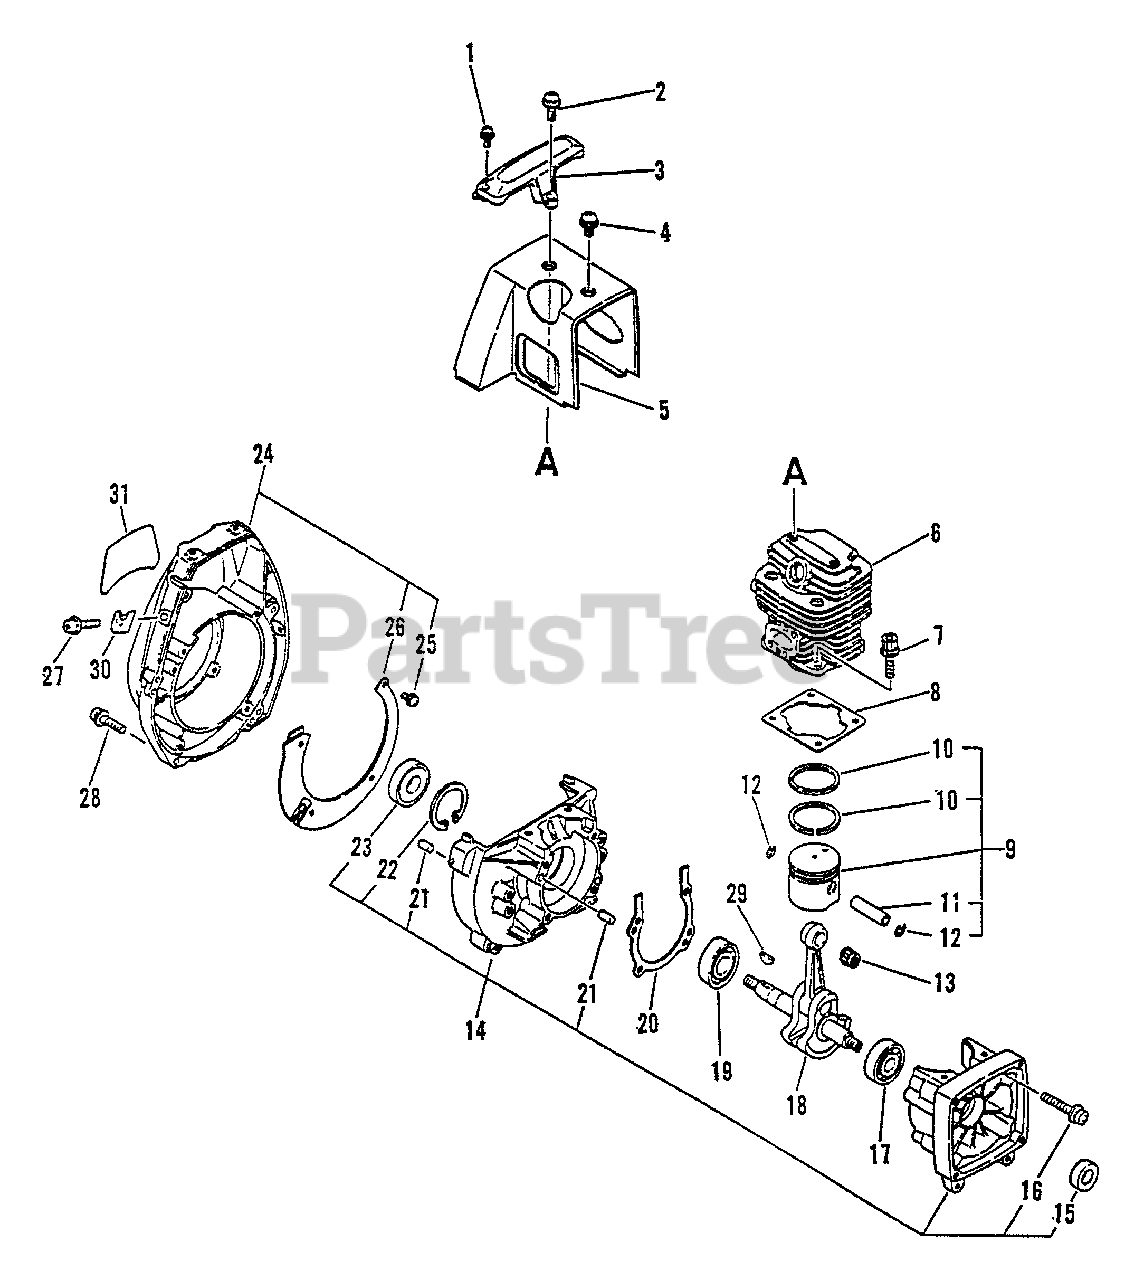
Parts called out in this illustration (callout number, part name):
1	SCREW - 4X14
2	SCREW - 5X16
3	GUARD - TOP
4	SCREW - 5X10
5	COVER, ENGINE
6	CYLINDER
7	SCREW - 5X20
8	GASKET, CYLINDER
9	PISTON KIT
10	RING, PISTON
11	PIN, PISTON
12	RING, RETAINING
13	BEARING, NEEDLE
14	CRANKCASE KIT
15	SEAL, OIL
16	SCREW - 5X30
17	BEARING, BALL - 6201
18	CRANKSHAFT ASSY
19	BEARING, BALL - 6202
20	GASKET, CRANKCASE
21	PIN - LOCATING
22	RING, RETAINING - 35
23	SEAL, OIL
24	FAN CASE ASSY
25	SCREW - 4X8
26	SHIELD, FAN
27	SCREW - 4X10
28	SCREW - 5X25
30	HOLDER, CABLE
31	LABEL - MODEL
31	GASKET KIT
31	GASKET, CRANKCASE
31	GASKET, CYLINDER
31	GASKET, INTAKE
31	GASKET, EXHAUST
